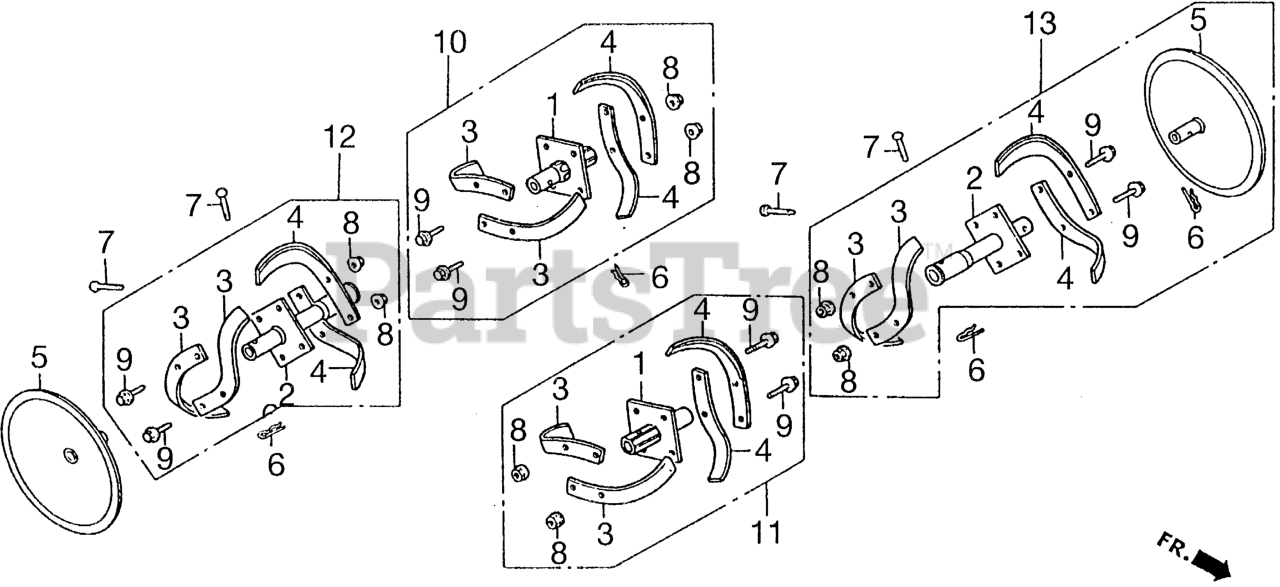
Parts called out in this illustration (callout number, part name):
1	PIPE, MAIN ROTOR
2	PIPE, ROTOR (OUTER)
3	TINE A, ROTOR
4	TINE B, ROTOR
5	DISK, SIDE
6	PIN, SNAP (7MM)
7	PIN, WHEEL (8X43)
8	NUT, FLANGE (8MM)
9	BOLT, FLANGE (8X20) Use up to Engine SN 1609606.
10	ROTOR ASSY., R. MAIN
11	ROTOR ASSY., L. MAIN
12	ROTOR ASSY., R. (OUTER)
13	ROTOR ASSY., L. (OUTER)
